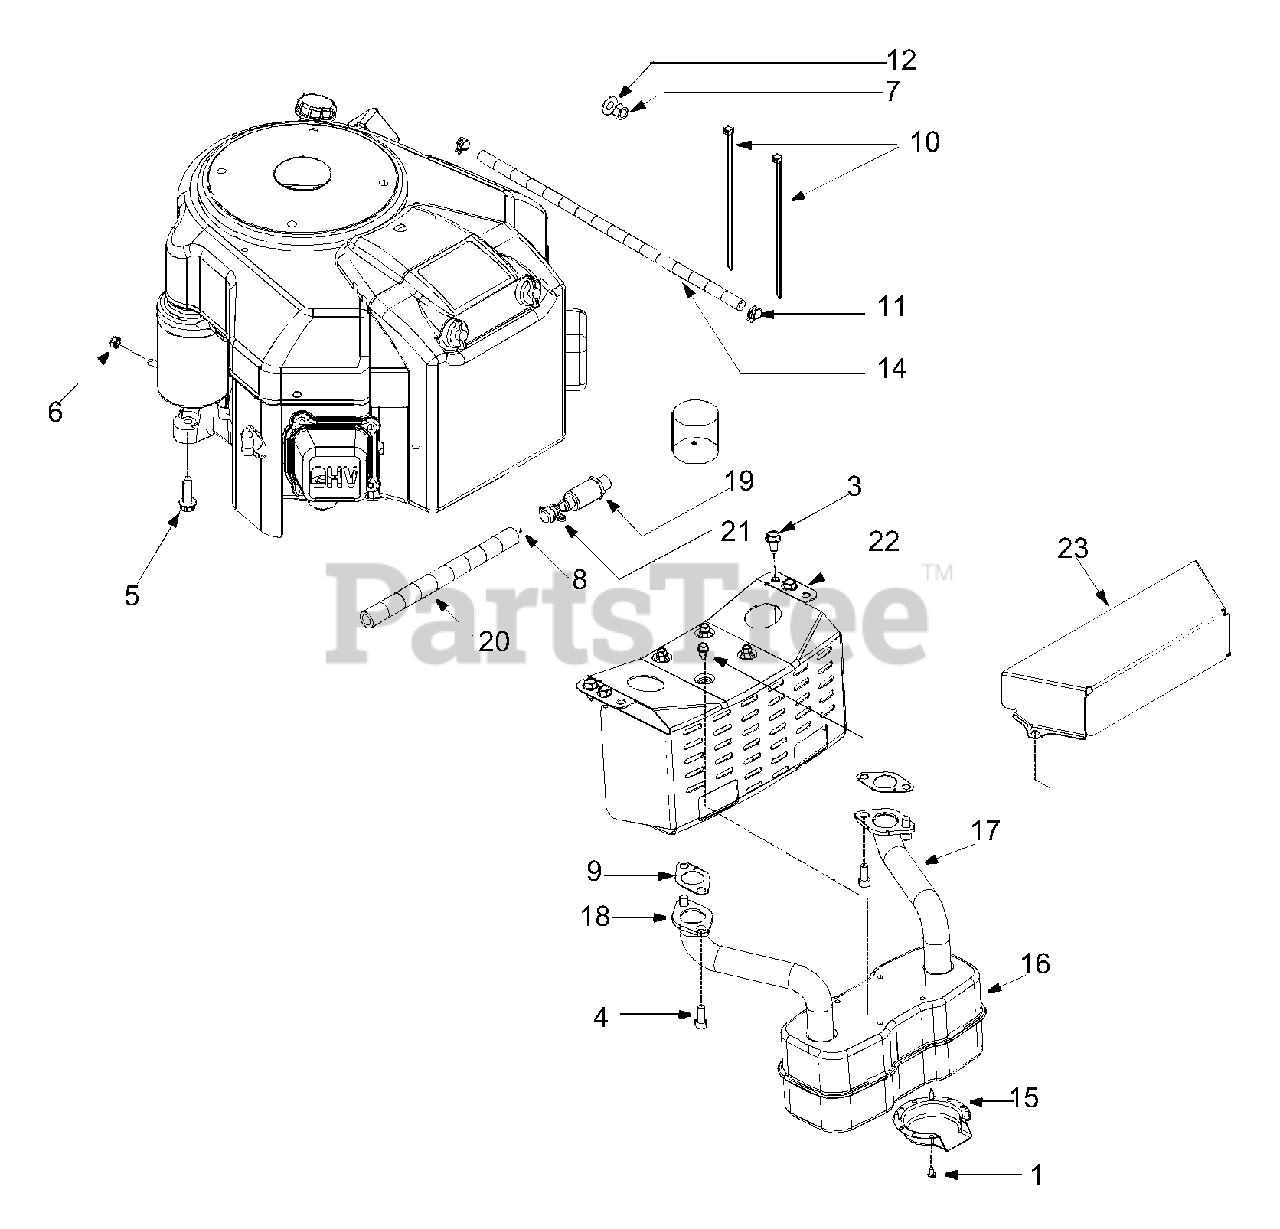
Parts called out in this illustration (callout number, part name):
1	AB Screw #8-18 x 0.5
2	TT Screw 1/4-20 x 0.5
3	AB Screw 5/16-12 x 0.5
4	Socket Hd Scr 5/16-18 x .750
5	TT Screw 3/8-16 x 1.25
7	Hex Nut 3/8-16
8	Pipe Sealant
9	Exhaust Gasket
13	SAE 30W Oil
14	Fuel Line Hose
15	Muffler Deflector
16	Muffler
17	Exhaust Pipe LH
18	Exhaust Pipe RH
19	Oil Drain
20	OIl Drain Hose extension
21	Oil Drain Cap
